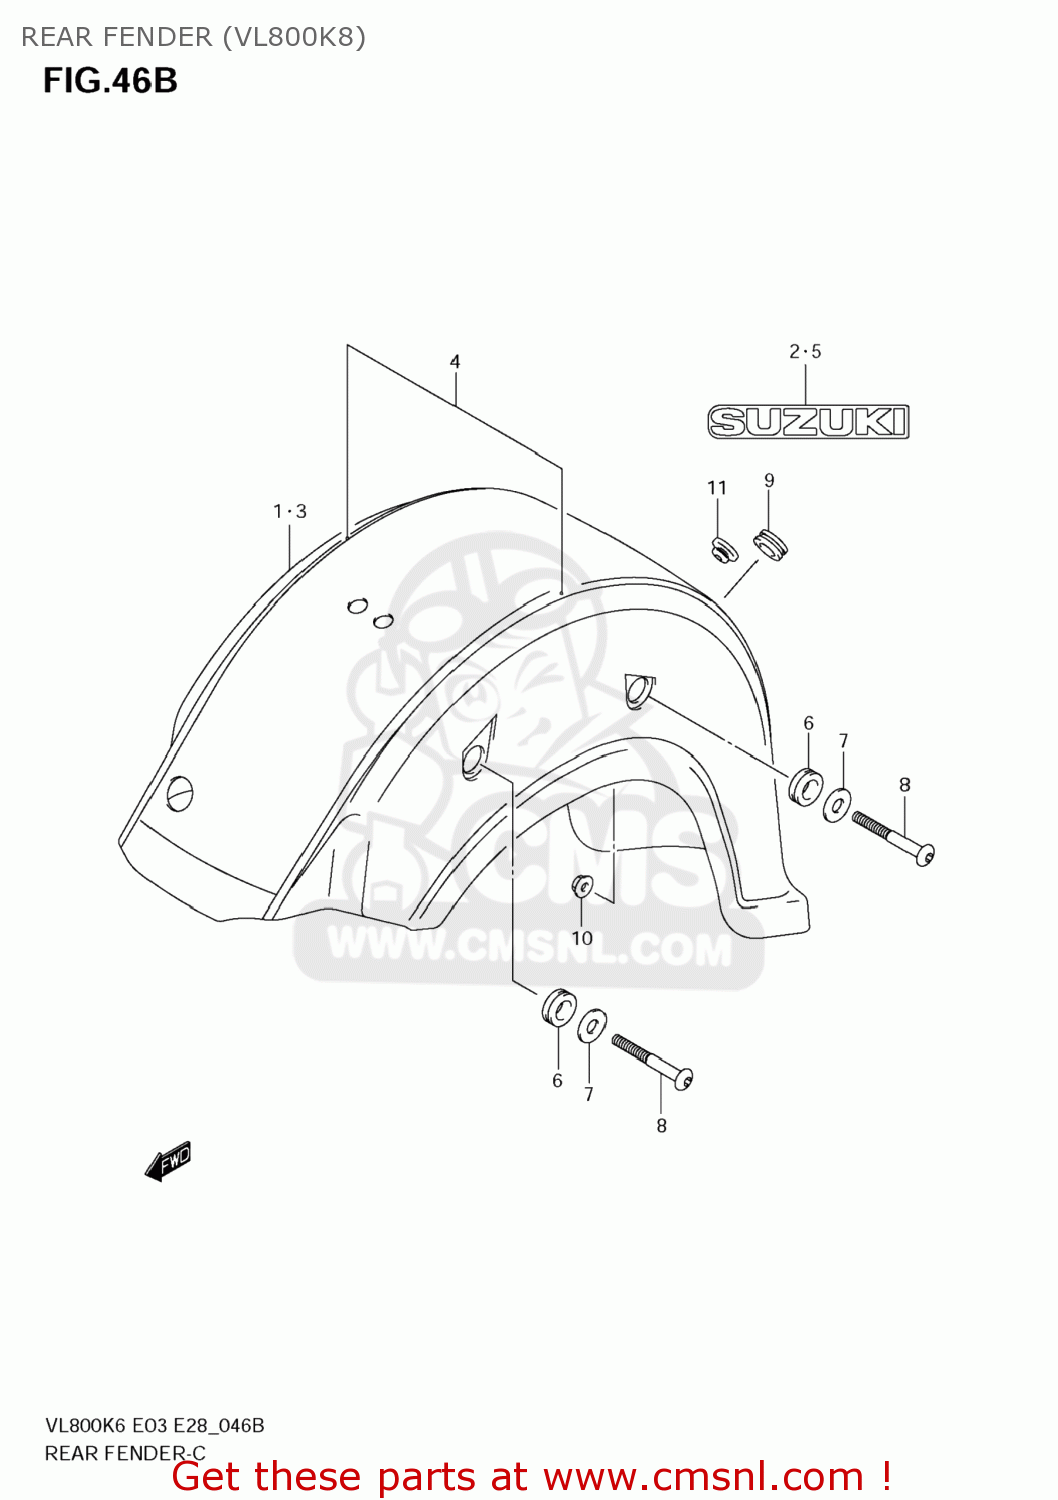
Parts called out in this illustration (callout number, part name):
1	FENDER,RR
2	EMBLEM,SUZUKI
3	FENDER,RR
4	TAPE SET,RR FENDER
5	EMBLEM,SUZUKI
6	CUSHION,FRAME COVER UPR RR
7	WASHER(15.5X26X2.3)
8	BOLT,RR FENDER
9	CUSHION
10	NUT
11	CUSHION
